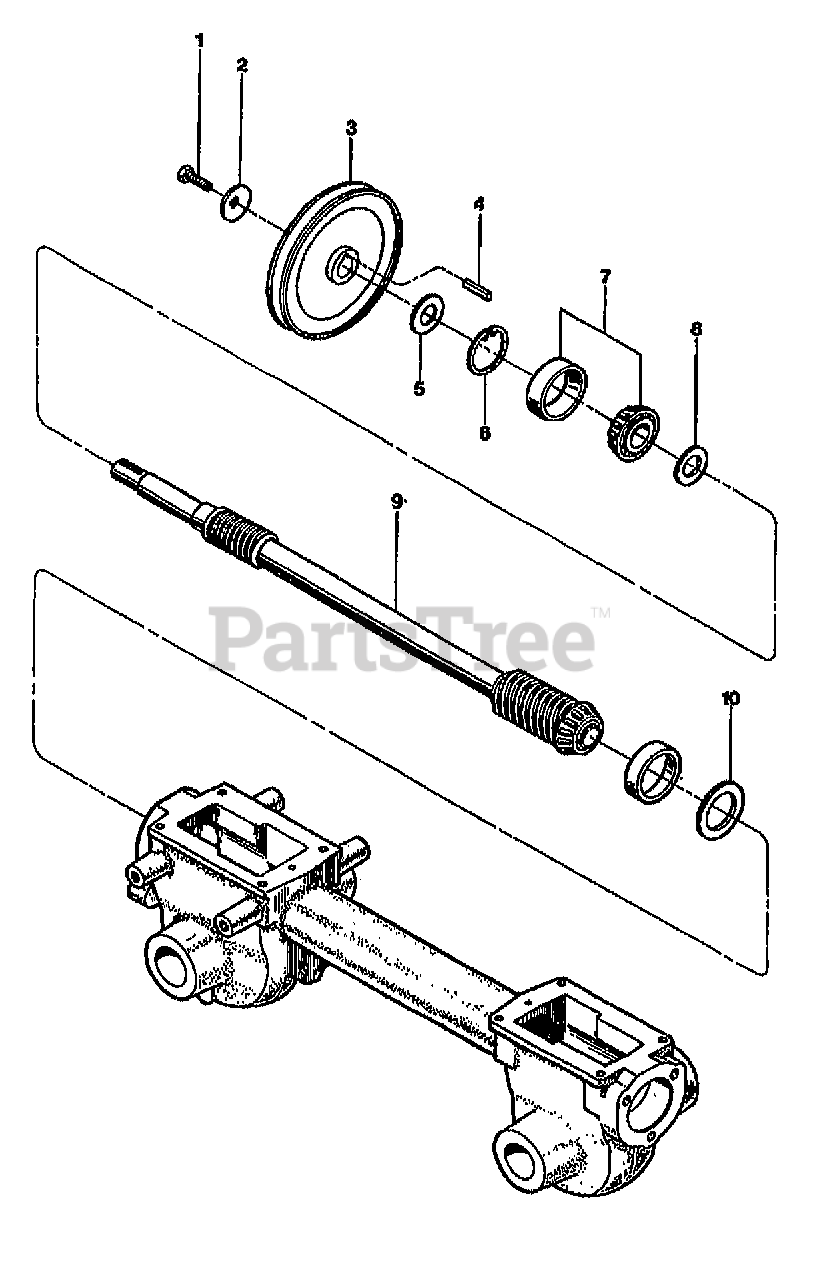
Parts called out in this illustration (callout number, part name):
1	SCR-HH 5/16-24X.75 G5 ZP
2	WASHER-.827X.331X.098
3	PULLEY-TRANSMISSION
4	KEY-.188 SQX1.0
5	WASHER-SHLDR HARDENED
6	RING-RETAINING 5000-181
7	KIT-BRG CONE&RACE-DRIVESHAFT
8	WASHER-#1.25X.75X.06
9	DRIVESHAFT-MACH
10	SHIM-1.75X1.5X.01
10	SHIM-1.75X1.5X.03
10	SHIM-1.75X1.5X.005
10	SHIM-1.75X1.5X.062
10	SHIM SET-DRIVESHAFT-HORSE (INCL. 2 #1224-1, 2 #1224-2, 1 #1224-3, 1 #1224-4)
